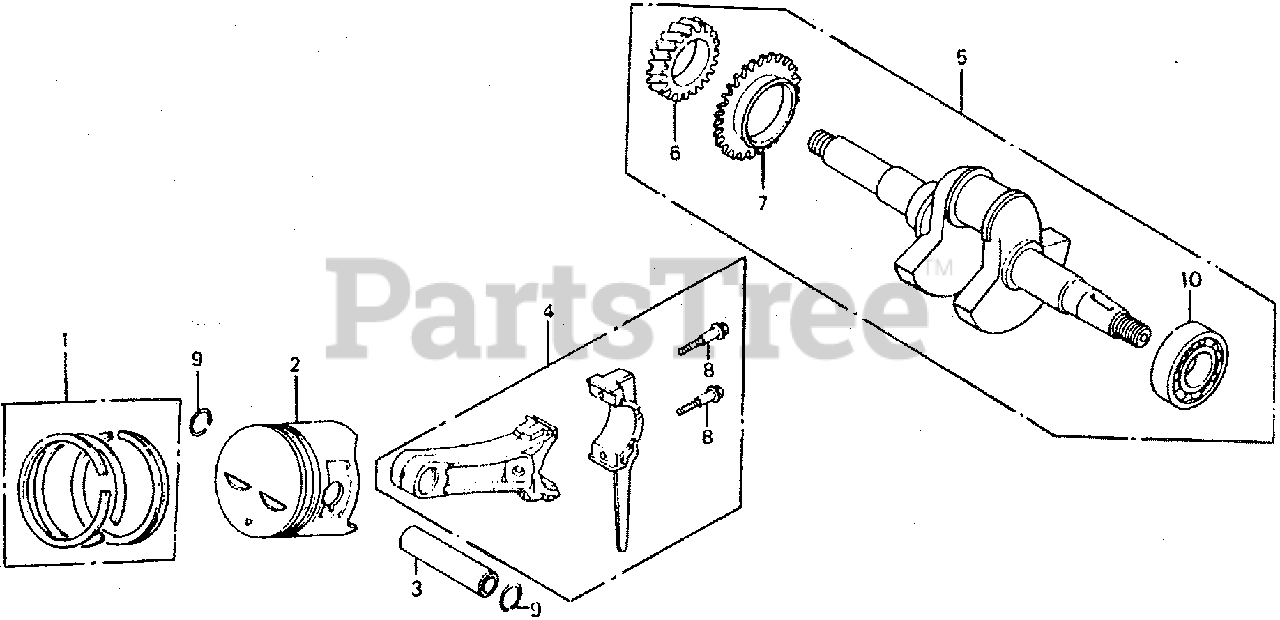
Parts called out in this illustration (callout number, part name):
1	RING SET, PISTON (STD)
1	RING SET, PISTON (OS 0.25)
1	RING SET, PISTON (OS 0.50)
1	RING SET, PISTON (0.75)
2	PISTON (STD)
2	PISTON (OS 0.25)
2	PISTON (OS 0.50)
2	PISTON (0.75)
3	PIN, PISTON
4	ROD ASSY., CONNECTING (STD)
4	ROD ASSY., CONNECTING
5	CRANKSHAFT (W-TYPE)
6	GEAR, TIMING
7	GEAR, GOVERNOR DRIVE
8	BOLT, CONNECTING ROD
9	CLIP, PISTON PIN (18MM)
10	BEARING, RADIAL BALL (6206)
